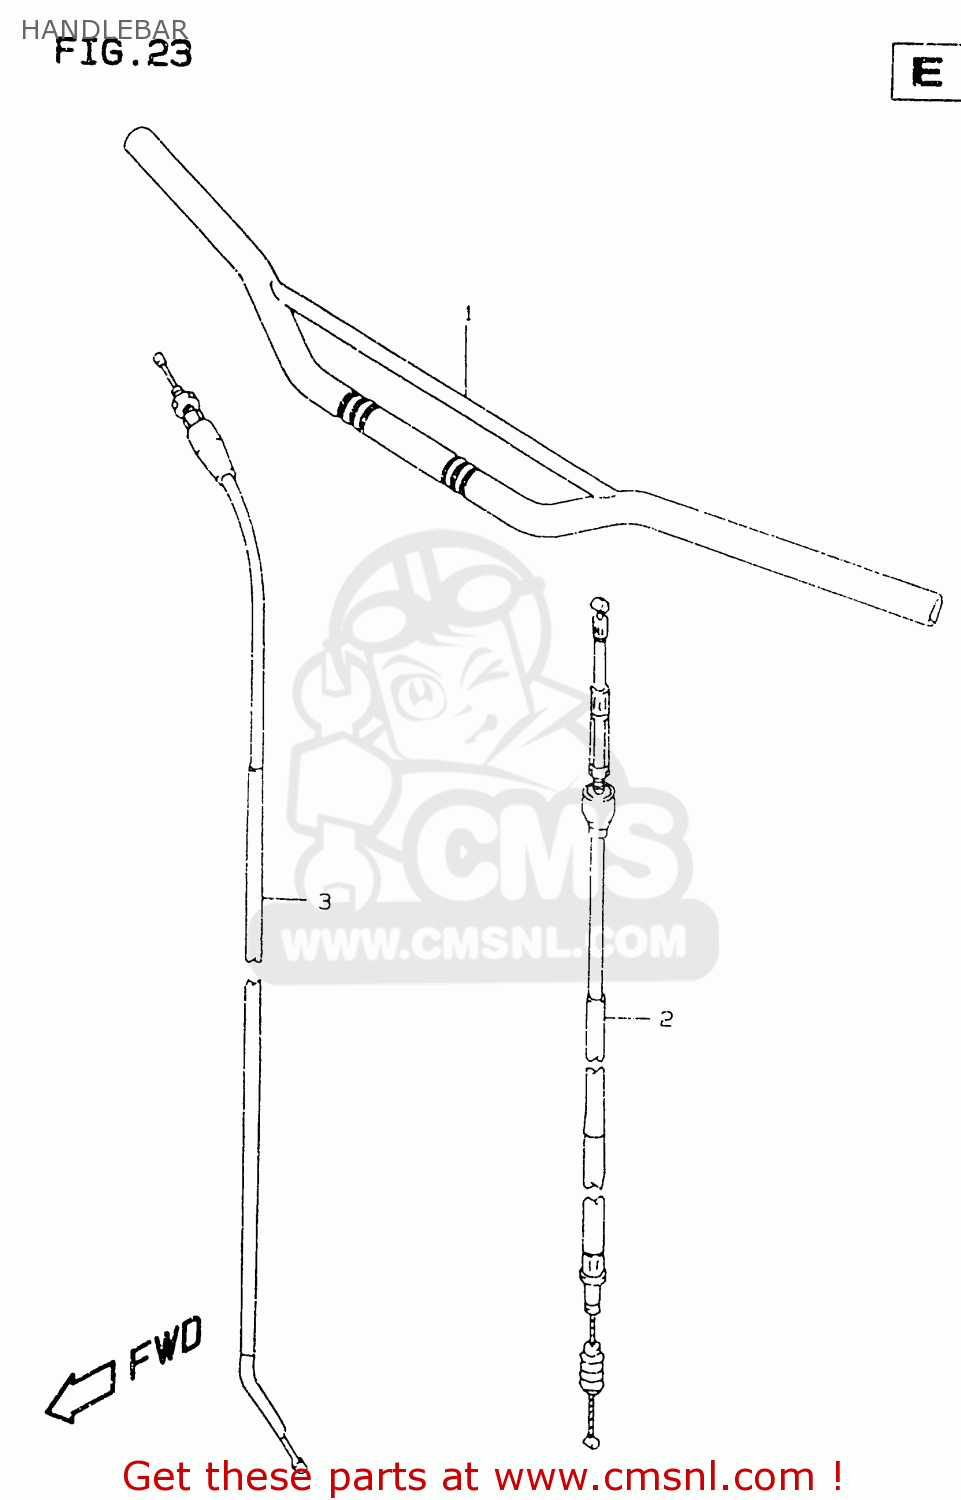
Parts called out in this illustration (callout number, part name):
1	HANDLEBAR COMP
2	CABLE ASSY,CLUTCH
3	CABLE ASSY,THROTTLE
